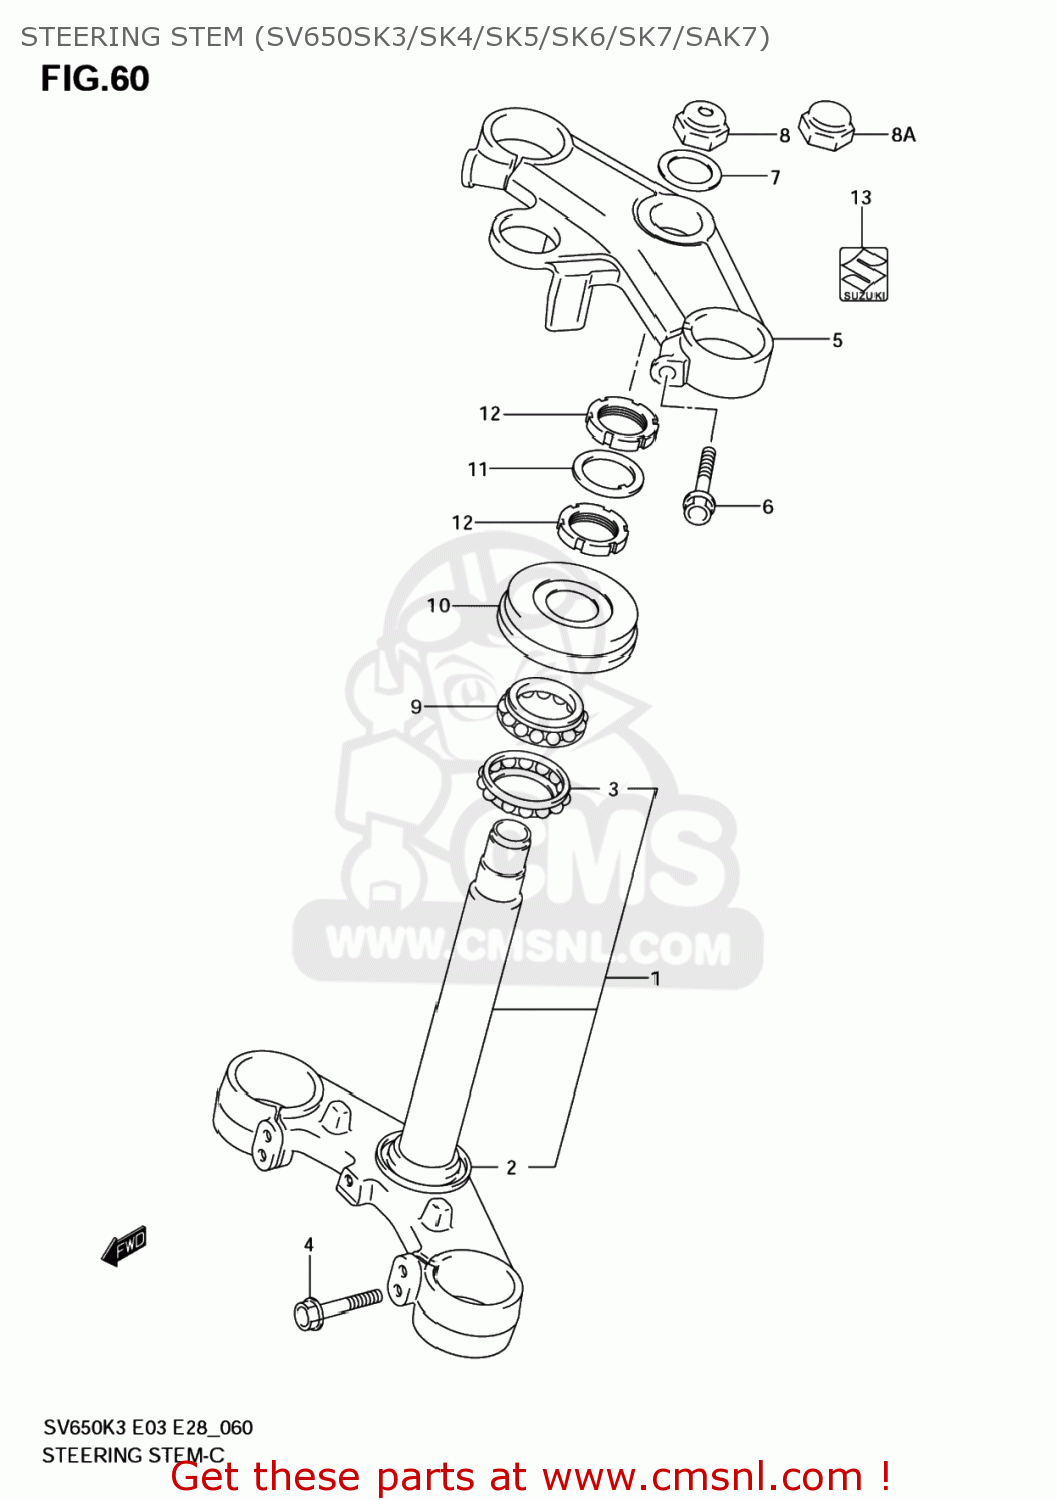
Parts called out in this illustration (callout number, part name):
1	STEM,STEERING
2	SEAL,STEERING LWR
3	BEARING(30X55X17)
4	BOLT(8X40)
5	HEAD,STEERING STEM
6	BOLT(8X40)
7	WASHER
8	NUT
8A	NUT
9	BEARING(30X55X17)
10	SEAL,STEERING UPR DUST
11	WASHER,STEERING STEM
12	NUT,STEERING STEM
13	EMBLEM,S
